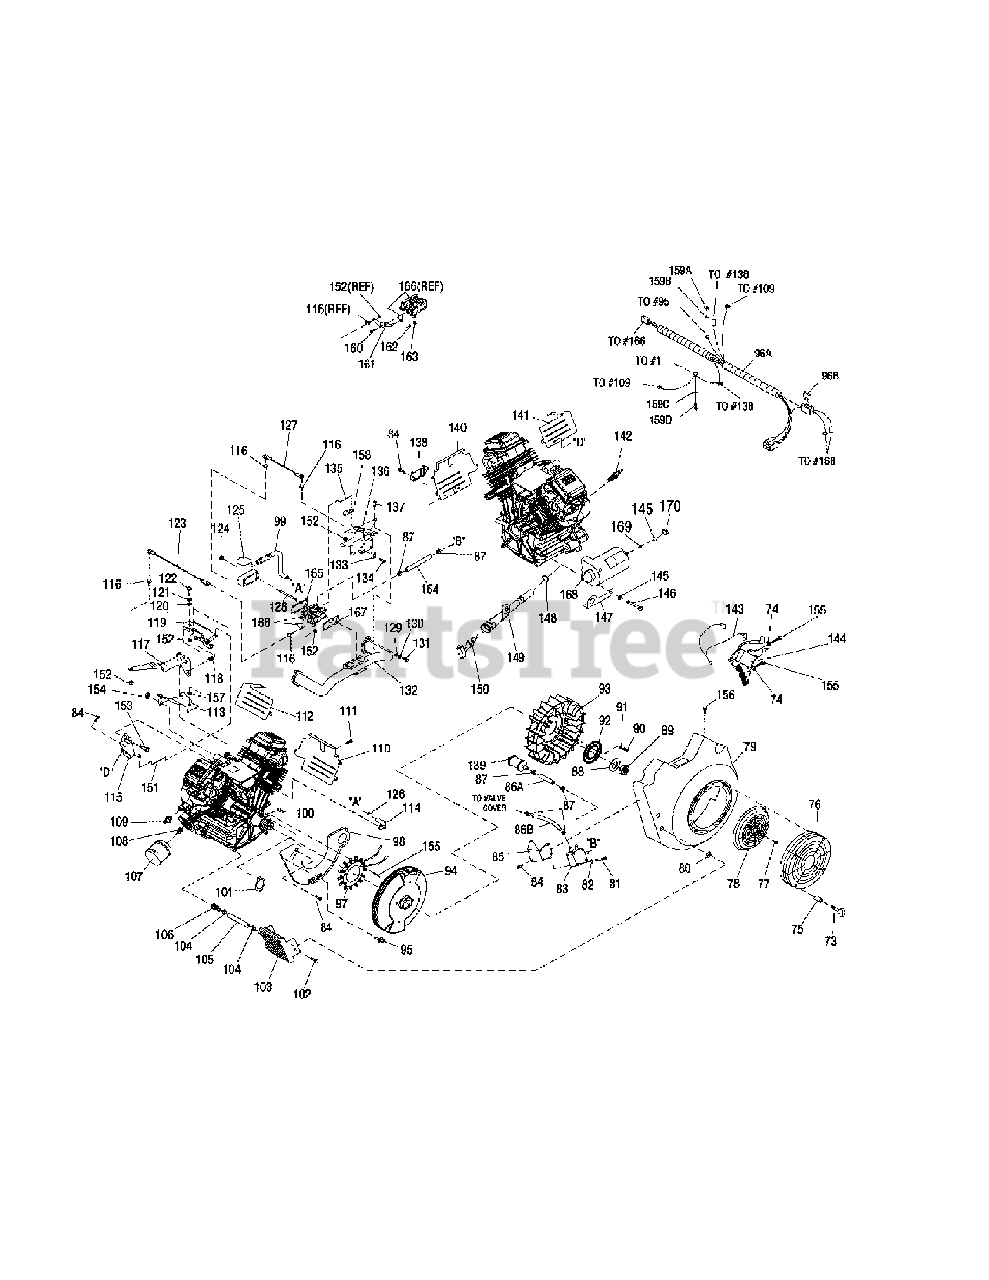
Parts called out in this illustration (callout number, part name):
73	KNOB AIR CLEANER
74	WASHER, LOCK M6-1/4"
75	SPACER, ROTATING SCREEN GUARD
76	GUARD, ROTATING SCREEN
77	SCREW, #10 SHEET METAL
78	SCREEN, ROTATING
79	HOUSING, BLOWER VERTICAL
80	NUT, GROMMET 1/4 PLUG
81	SCREW PPHM M4-0.7 x 40
82	WASHER, LOCK M4
83	PUMP, IMPULSE
84	SCREW TAPTITE M6-1.0 x 10 YELLOW CHROME
85	BRACKET, FUEL PUMP
86A	HOSE 1/4" ID x 2" LONG
86B	HOSE 1/4" ID x 7" LONG
87	CLAMP HOSE BAND 1/4
88	WASHER, M24
89	NUT, HEX M24
90	SCREW HHC M8-1.25 x 10 G8.8
91	WASHER SHAKEPROOF INT M8 SS
92	PLATE, FAN
93	FAN, NYLON
94	FLYWHEEL ASSEMBLY
95	INSULATOR ASSEMBLY IGNITION
96A	VS WIRE HARNESS W/ FUSE
96B	30 AMP FUSE
97	ASSEMBLY, STRATOR W/LUGS
98	PLATE, BACKING WITH OIL COOL
99	ASSY. BREATHER TUBE
100	KEY, WOODRUFF 4 x 19D
101	GASKET, MANIFOLD / PORT
102	PLASTITE, 1/4 - 15 x 3/4
103	COOLER, OIL
104	CLAMP HOSE .38 - .87
105	HOSE, 3/8" I.D x 6" LONG
106	BARBED STR 1/4NPT x 3/8 WITH VIBRA SEAL
107	FILTER OIL D 69 x 64 LONG
108	NIPPLE, 34"-16 UNF
109	SWITCH, OIL PRESS
110	WRAPPER, LOWER CYLINDER 1
111	SCREW THTT #10-24 x 3/8"
112	WRAPPER, UPPER CYLINDER 1
113	BRACKET, SUPPORT-GOVERNOR ADJUST
114	HOSE, BLOWER HSG TO BREATHER
115	ASSY, IDLE SPEED SUPPORT BRACKET
116	STUD, BALL M3-0.5
117	ASSY, GOVERNOR LEVER
118	SPRING, GOVERNOR
119	ASSY, IDLE SPEED ADJUST W/ GROMMET
120	WASHER, FLAT M5
121	WASHER LOCK M5
122	SCREW, HHC M5-0.8 x 10
123	ROD, GOVERNOR
124	NUT LOCK FLANGE M6-1.0
125	ADAPTOR, CARB-AIRBOX, M6 BOSSES
126	HOSE CLAMP, BAND 12 MM I.D.
127	ASSEMBLY, IDLE SPEED ADJUSTMENT ROD
128	STUD, METRIC
129	WASHER, FLAT M8
130	WASHER, LOCK M8
131	SCREW, SHC M8-1.25 x 30
132	MANIFOLD.INTAKE 2BBL CARB
133	CLAMP, 3/16" COATED CABLE
134	SCREW, PPHM M5-0.8 x 12
135	ROD, CHOKE
136	ASSY, BELDEN BRACKET W/BELLCRANK
137	SCREW HHFC M6-1.0 x 8MM
138	REGULATOR, 20 AMP
139	FILTER, FUEL
140	WRAPPER, LOWER CYLINDER 2
141	WRAPPER, UPPER CYLINDER 2
142	SPARK PLUG BKR4E
143	ASSEMBLY, GROUND WIRE
144	ASSEMBLY, IGNITION COIL
145	WASHER, LOCK M8-5/16
146	SCREW, HHC M8-1.25 x 85 G8.8
147	LIFT HOOK, STARTER
148	O-RING, OIL CLR
149	TUBE, DIPSTICK
150	ASSEMBLY, DIPSTICK W/ HANDLE
151	ROD, IDLE ADJUSTMENT
152	NUT, LOCK HEX M3-0.5
153	SCREW, SHC M10-1.5 x 75 G10.9
154	NUT, LOCK FL-SERRATED M10-1.5
155	SCREW, TAPTITE M6-1.0 x 25
156	SCREW, FHHC M6-1.0 x 12 W/M5 HEX
157	WASHER NYLON 0.357" I.D.
158	BUSHING, GOVERNOR ROD
159A	NUT HEX #8-32
159B	WASHER LOCK #8-M4
159C	WASHER LOCK M3
159D	SCREW PPHM M3-0.5 x 8
160	SCREW, PPHM #10-32 X3/8
161	BRACKET, THROTTLE
162	WASHER, LOCK #10
163	NUT, HEX #10-32
164	HOSE 1/4"ID x 11" LONG
165	GASKET, CARB TO SPACER
166	CARBURETOR DENI GVT990
167	GASKET, MANIFOLD TO CARB
168	STARTER, V-TWIN ENGINE
169	WASHER, FLAT M8
170	NUT, HEX M8-1.25 G8
